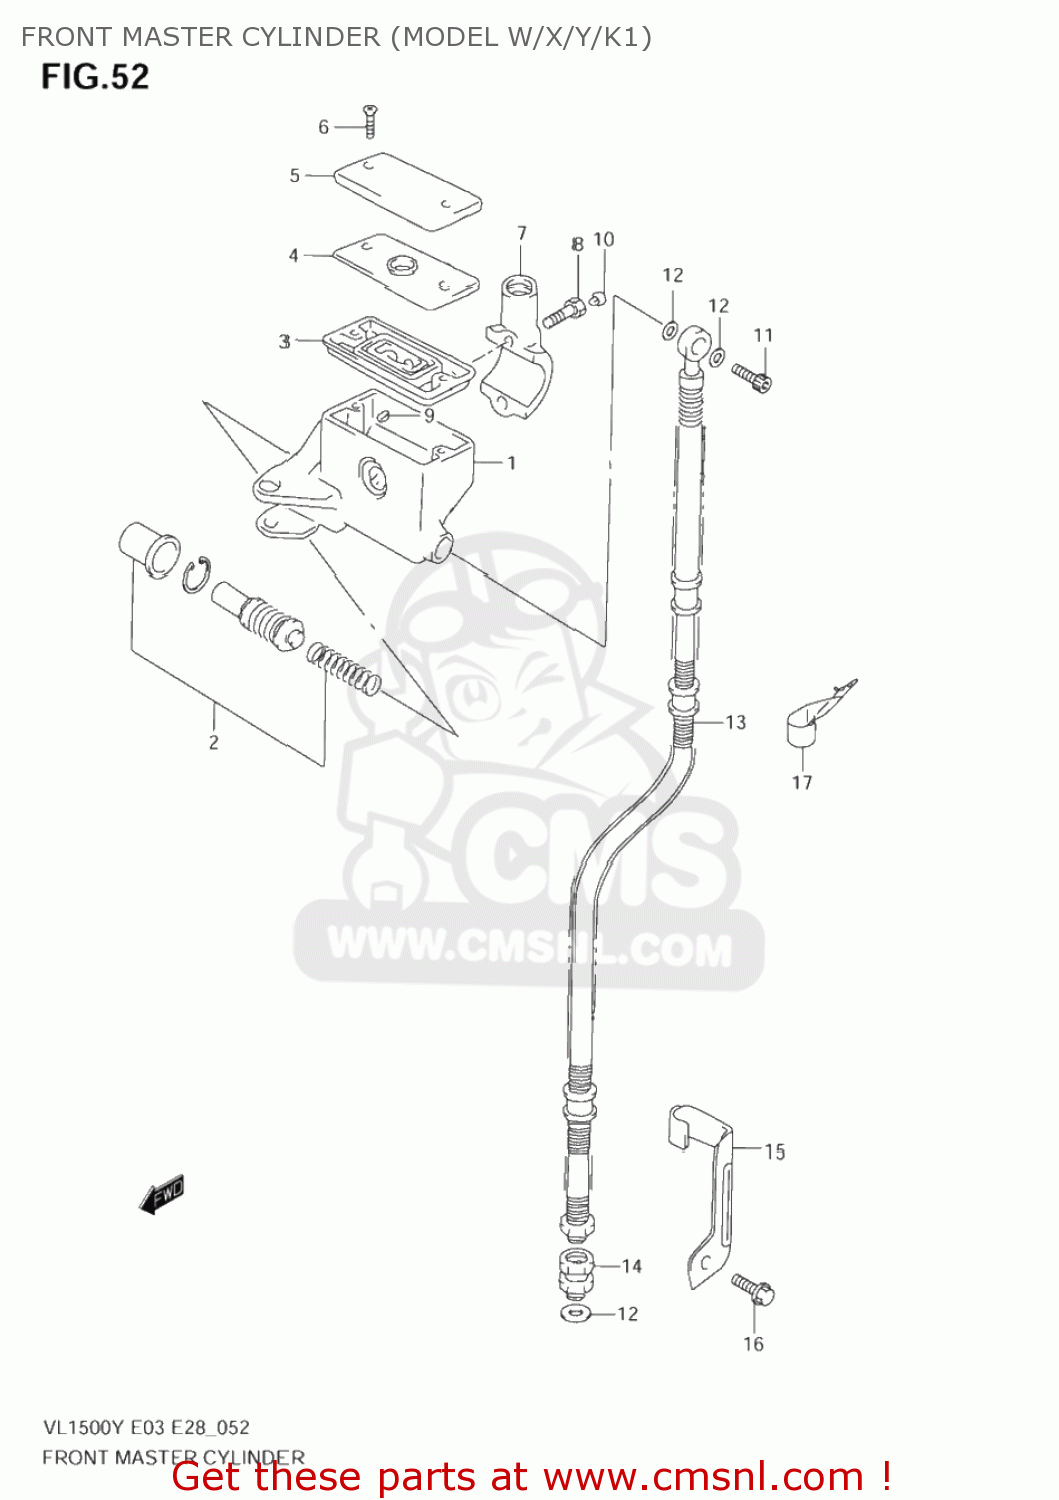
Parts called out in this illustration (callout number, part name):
1	CYLINDER ASSY,FR MASTER
2	PISTON/CUP SET
3	4
4	PLATE,DIAPHRAGM
5	CAP
6	SCREW
7	HOLDER
8	BOLT
9	PROTECTOR
10	CAP(OD:10)
11	BOLT UNION
12	WASHER(10X15X1.5)
13	HOSE,FR BRAKE
14	ADAPTER,BRAKE HOSE
15	CLAMP,FR BRAKE HOSE
16	BOLT
17	CLAMP,FR BRAKE HOSE UPR
